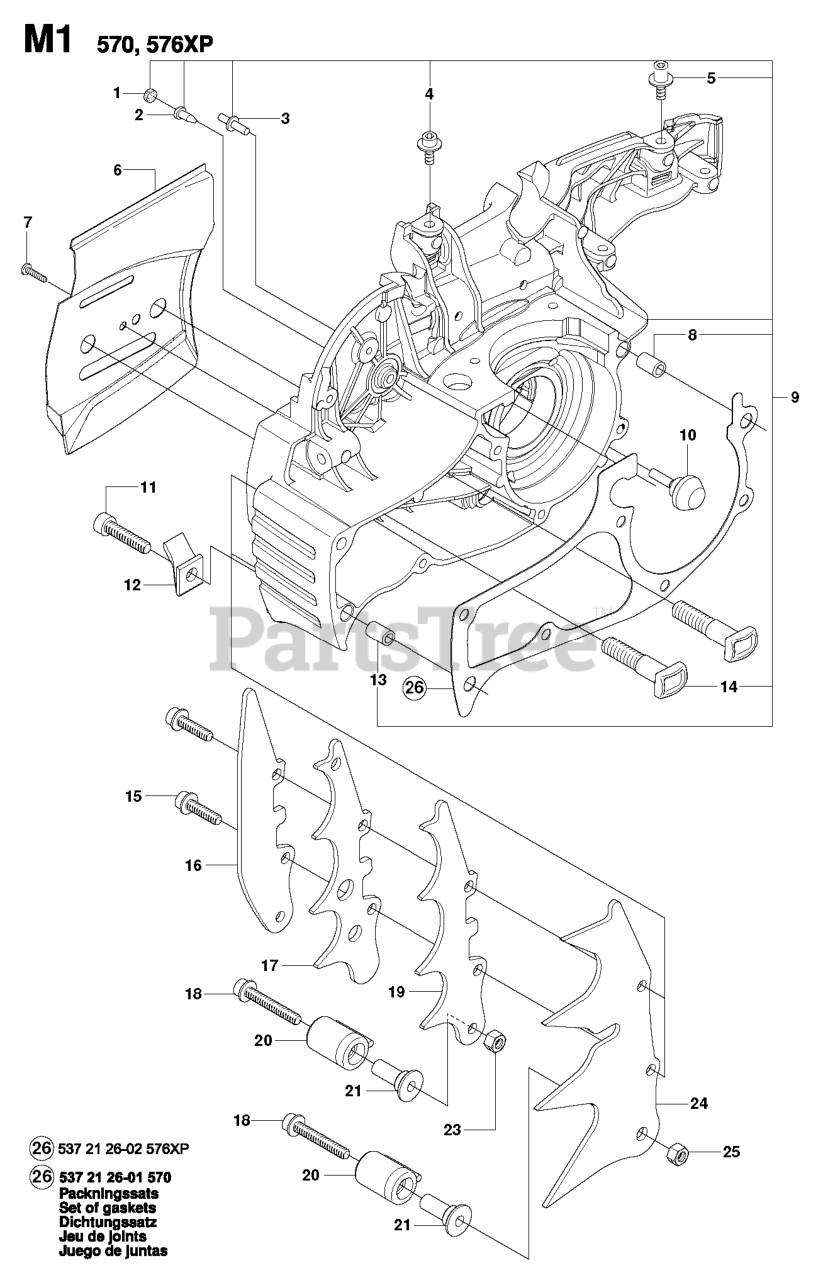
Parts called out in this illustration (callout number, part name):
1	PLUG
2	VALVE-CHECK (DUCKBILL)
4	SCREW IHSCM
5	SCREW IHSCM
9	CRANKCASE ASSY
9	RP CRANKCASE ASSEMBLY
12	CHAIN CATCHER
17	FELLING DOG
18	SCREW
19	FELLING DOG
21	CHAIN CATCHER
24	FELLING DOG
26	GASKET KIT
26	GASKET SET
